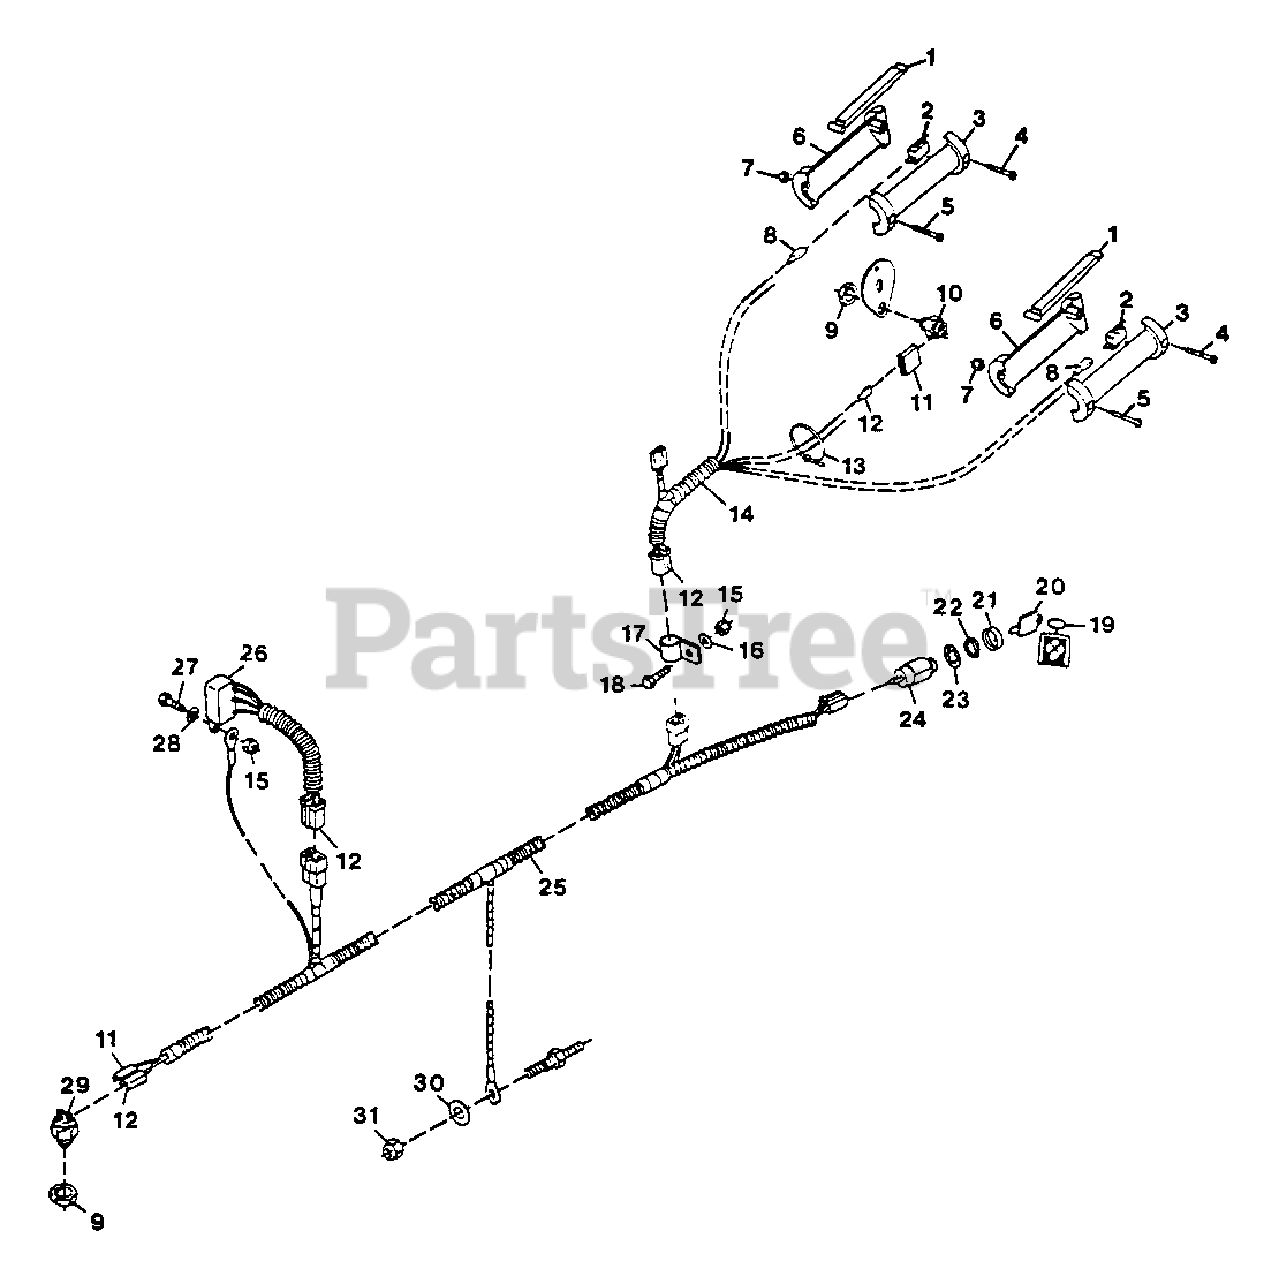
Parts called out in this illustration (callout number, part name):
1	Lever
2	Switch
3	Handle, L.H.
4	Screw, Machine 10-24x.625 PHD
5	Screw, Machine 10-24x1.50 PHD
6	Handle, R.H.
7	Nut, Lock 10-24
8	Terminal, Female
9	Nut, Stamped 9/16-18
10	Switch, Neutral Start
11	Connector, 2-Wire Switch
12	Terminal
13	Tie Wrap, Black
14	Harness, Wiring Handlebar
15	Nut, Lock 1/4-20
16	Washer, Flat .281x.625x.065
17	Clamp, Nylon
18	Bolt, Hex 1/4-20x.75
19	Chain, Key
20	Key, Ignition Switch
21	Boot
22	Nut, 9/16-24
23	Washer, Lock 5/8 Int. Tooth
24	Switch
25	Harness, Wiring
26	Module, Interlock Recoil
27	Bolt, Hex 1/4-20x.625
28	Washer, Lock 1/4 Int. Th.
29	Switch, Interlock
30	Washer, Flat .469x.938x.065
31	Nut, Lock 3/8-16
